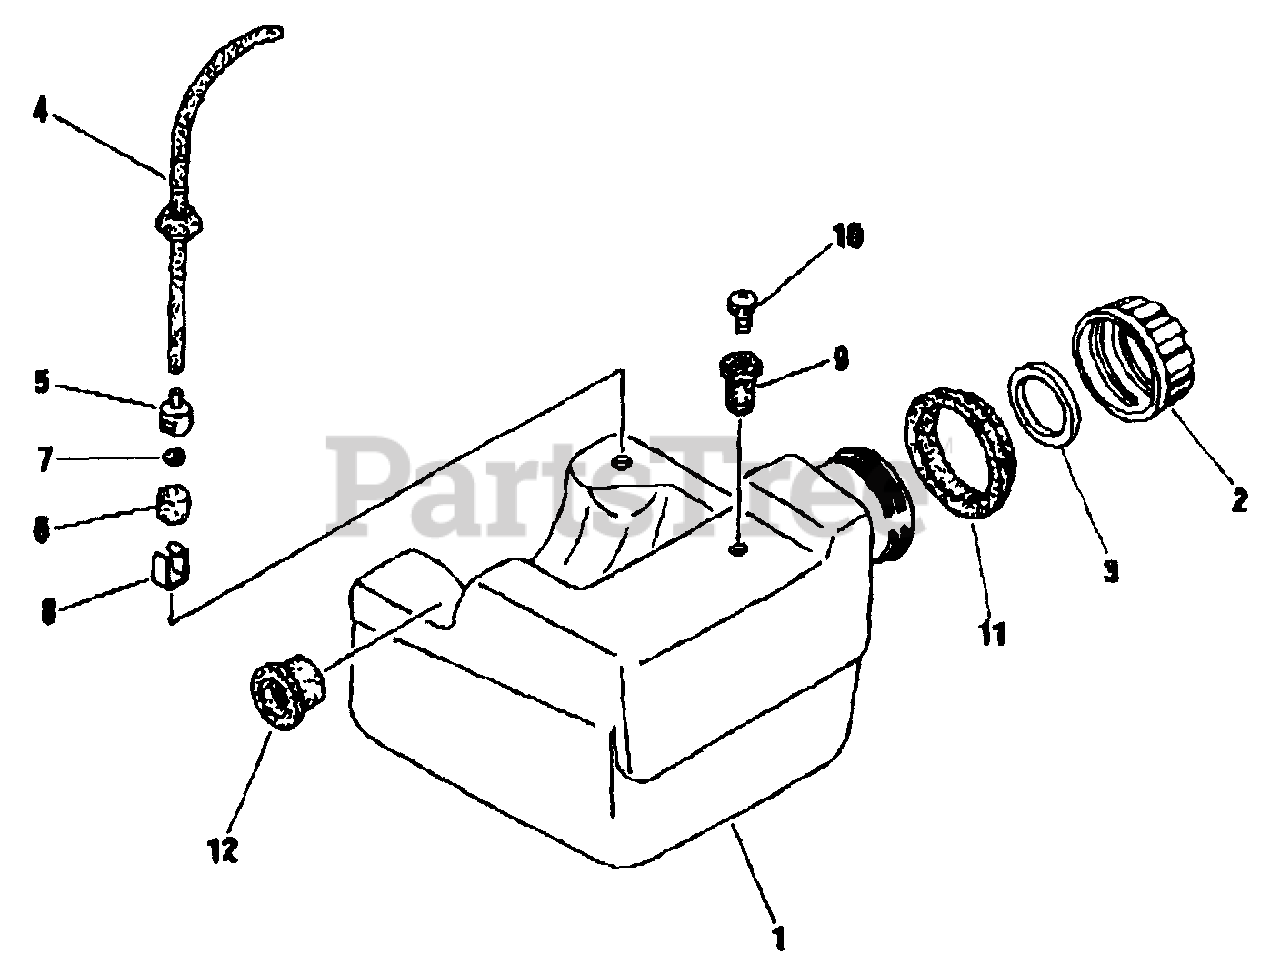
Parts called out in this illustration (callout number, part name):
1	TANK, FUEL
2	CAP, FUEL
3	GASKET, CAP
4	FUEL PIPE ASSY
5	WEIGHT, FUEL FILTER
6	FILTER, FUEL
7	ELEMENT, FILTER - SMALL
8	CLIP, FILTER
9	BODY, BREATHER
12	CUSHION
